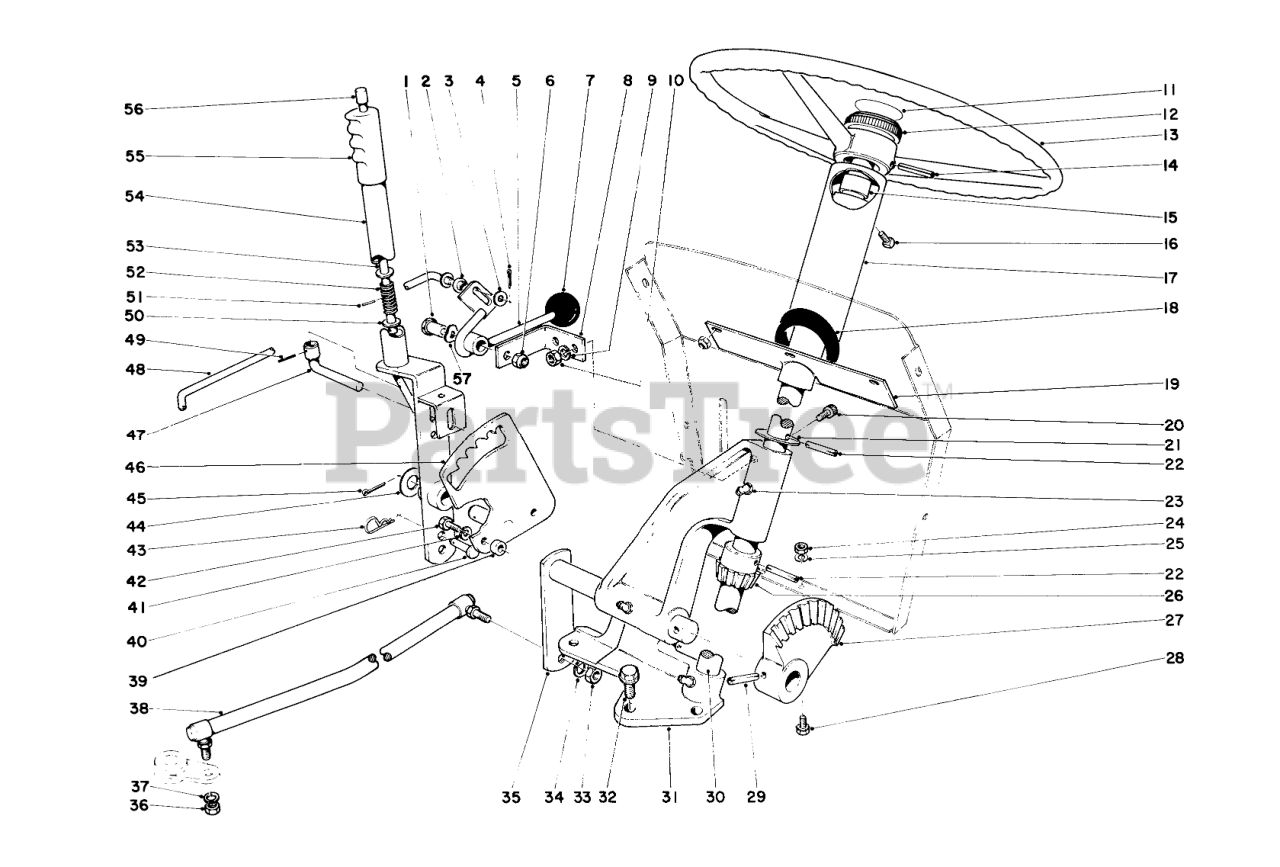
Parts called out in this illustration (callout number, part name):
2	Bushing
3	WASHER-FLAT
4	PIN-COTTER
5	Clutch Lever
6	NUT-LOCK, CONE
7	KNOB-CONTROL
8	Idler Bracket
9	WASHER-LOCK
10	NUT-HEX
11	Decal Steering Cap
12	Steering Cap
13	Steering Wheel
14	PIN-ROLL
15	BUSHING
16	SCREW-SQH
17	Cover Steering Support
18	Grommet
19	Steering Tube Incl. Ref. No. 15
20	Screw
21	WASHER-FLAT
22	PIN-ROLL, SLOTTED
23	Grease Fitting
24	NUT-HEX
25	WASHER-LOCK
26	Pinion Gear
27	Steering Gear
28	Sems Screw
29	1/4 X 2 DRIVELOK PIN
30	Steering Shaft
31	Steering Gear Support
32	Screw-HH
33	NUT-HEX
34	WASHER-LOCK
35	Steering W.A.
36	NUT-HJ
37	WASHER-LOCK
38	Steering Rod
39	Spacer
40	Pin
41	WASHER-LOCK
42	SCREW-HH
43	PIN-COTTER, HAIR
44	Washer
45	PIN-COTTER
46	Quadrant
47	Lift Lock
48	Clutch Rod
49	PIN-SPRING
50	Washer
51	PIN-ROLL
52	Spring
53	Lift Rod
54	Lower Handle
55	Handle Grip
57	Wavy Washer
